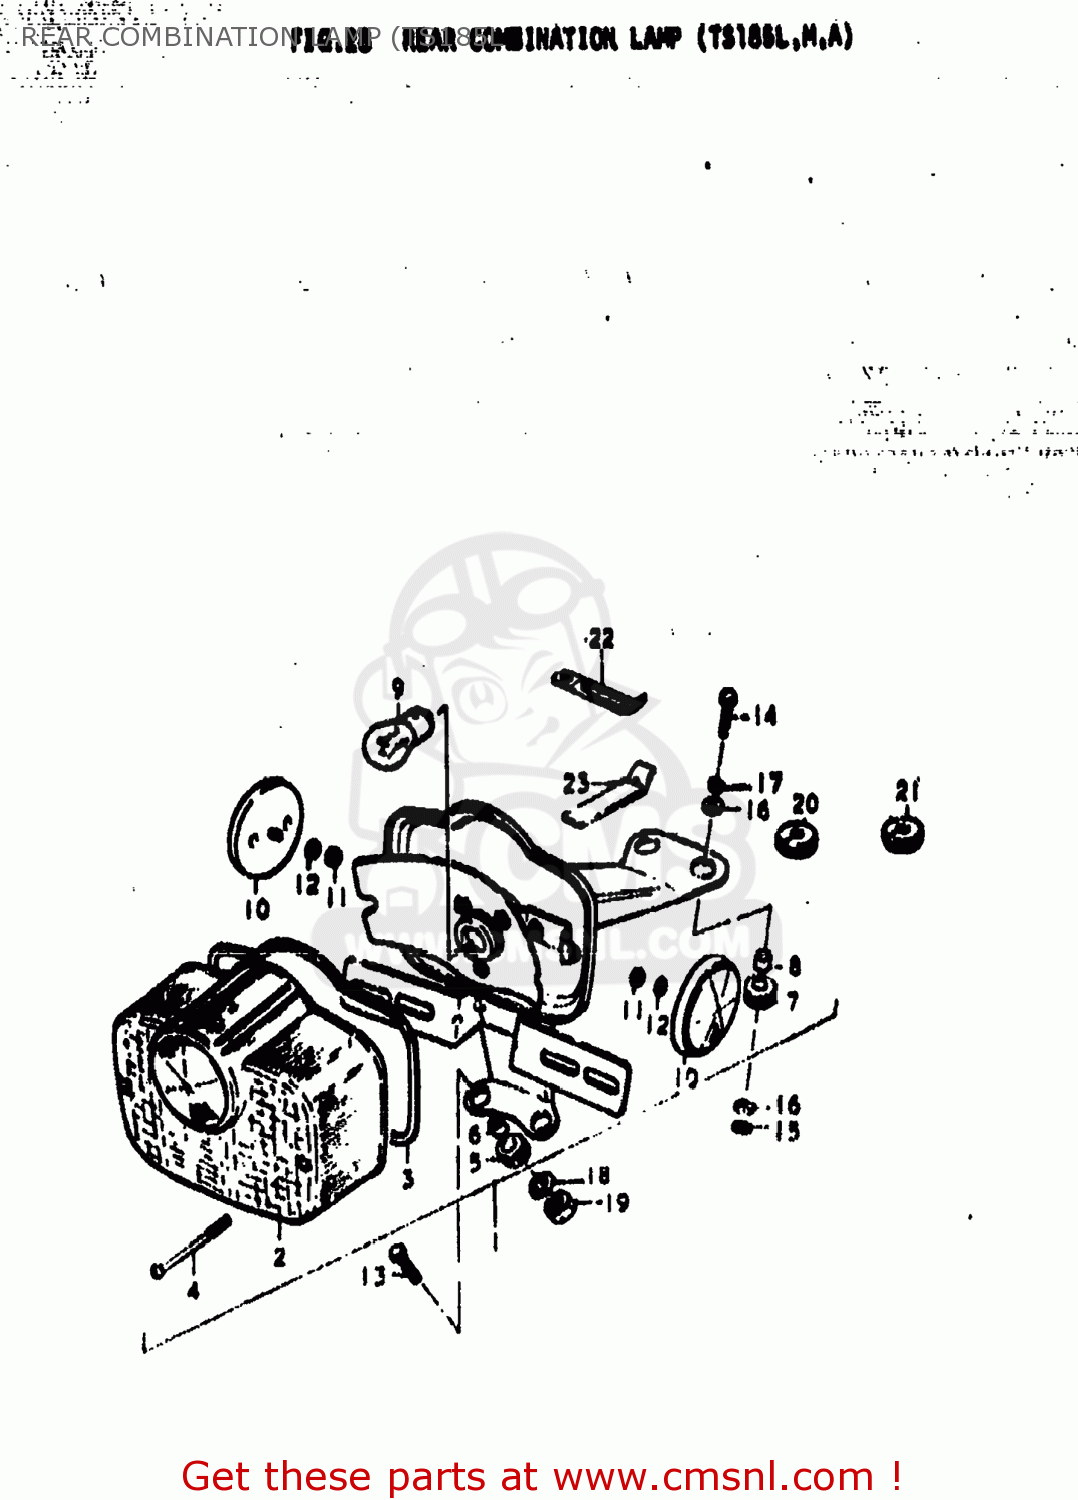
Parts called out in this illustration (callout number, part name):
1	LAMP ASSEMBLY,REAR COMBINATION
2	LENS,REAR COMBINATION LAMP
3	GASKET (NAS)
4	SCREW
5	CUSHION
6	SPACER,REAR COMBINATION LAMP
7	CUSHION
8	SPACER,REAR COMBINATION LAMP
9	BULB(6V32/3CP,STANLEY)
10	REFLECTOR,REFLEX
11	NUT
12	LOCK WASHER
13	BOLT
14	BOLT
15	LOCK WASHER
16	WASHER
17	LOCK WASHER
18	WASHER
19	NUT
20	GROMMET
21	GROMMET
22	CLAMP
23	CLAMP
